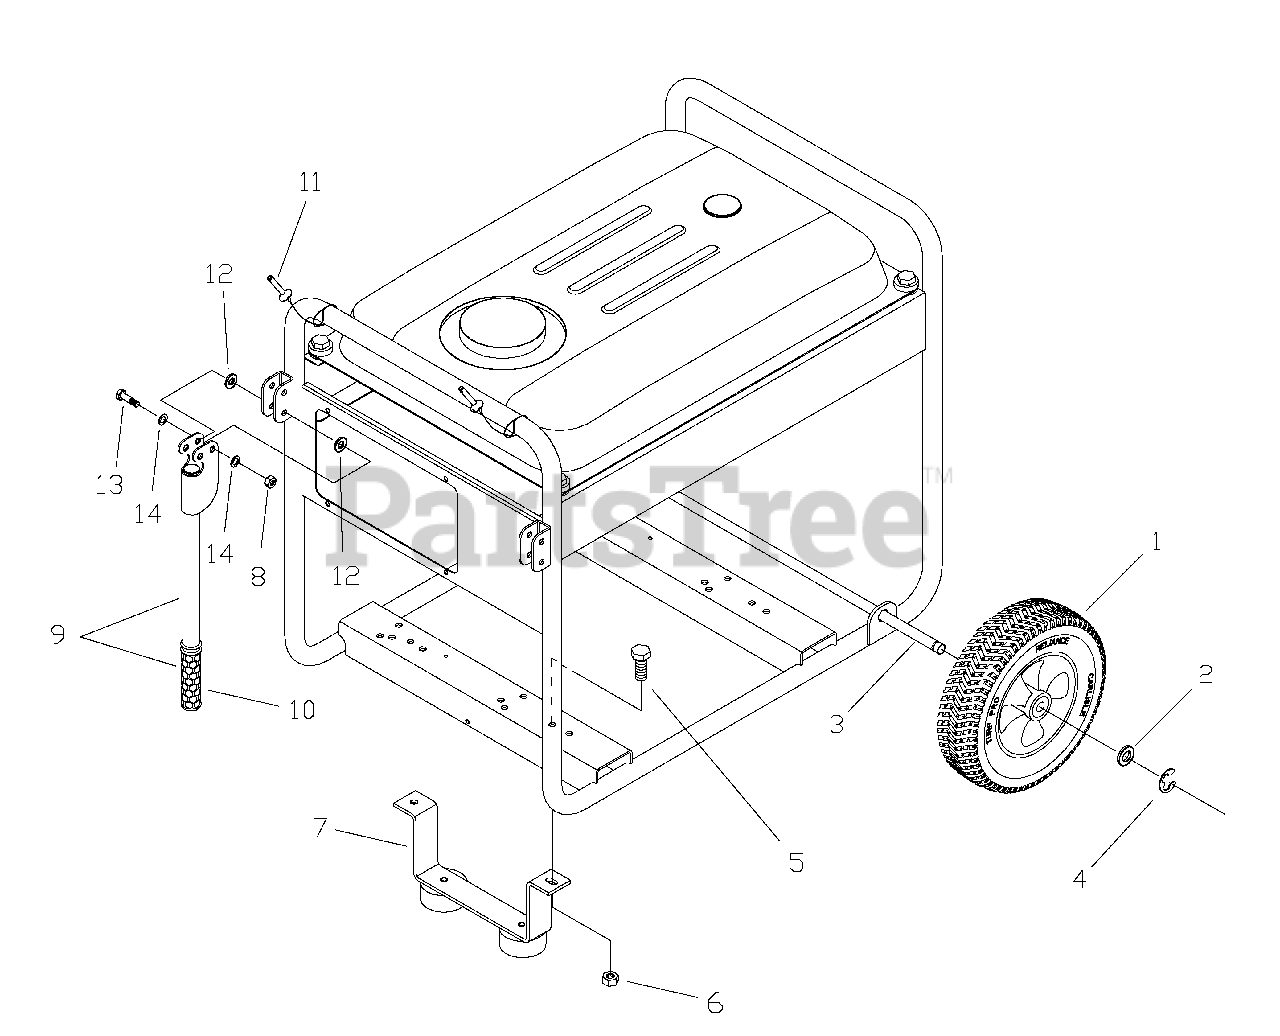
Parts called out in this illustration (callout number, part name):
2	WASHER, 5/8"
3	AXLE, 5/8"
4	E-RING
5	HHCS, M8 1.25 x 20
6	NUT, Flange Serrated, M8
7	ASSEMBLY, Support
8	NUT. Nylock, M8 - 1.25
9	ASSEMBLY, Handle with Grip
12	WASHER, Nylon, 1.2 x 0.346 x 0.03
13	HHCS, M8 - 1.25 x 45
14	WASHER, Flat, 5/16 - M8
